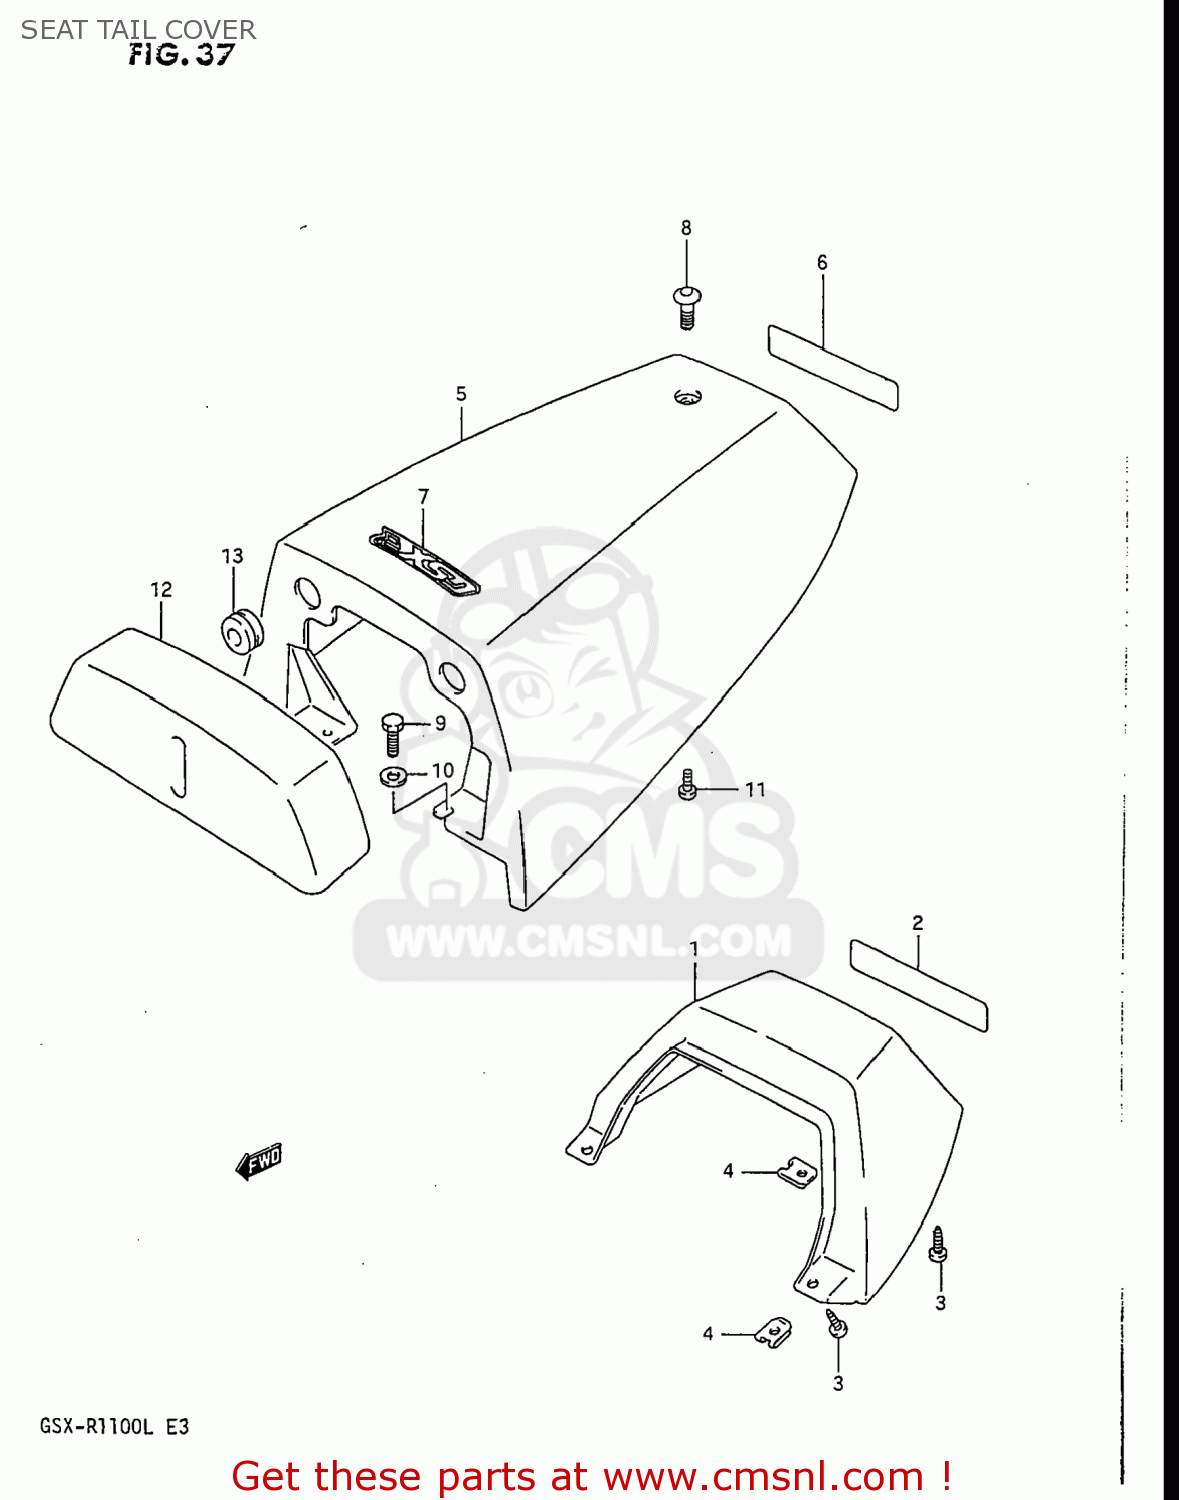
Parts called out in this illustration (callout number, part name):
1	COVER COMP,SEAT TAIL
2	EMBLEM
3	SCREW
4	NUT
5	BOX ASSEMBLY,SEAT TAIL
6	EMBLEM
7	EMBLEM,SEAT TAIL BOX
8	SCREW(6X16)
9	BOLT,M6X1X20
10	WASHER, LOWER
11	SCREW
12	BACKREST,SEAT
13	CUSHION
14	BOX SET,SEAT TAIL
15	EMBLEM
16	SCREW(6X16)
17	BOLT,M6X1X20
18	WASHER, LOWER
19	SCREW
20	BACKREST,SEAT
21	CUSHION
